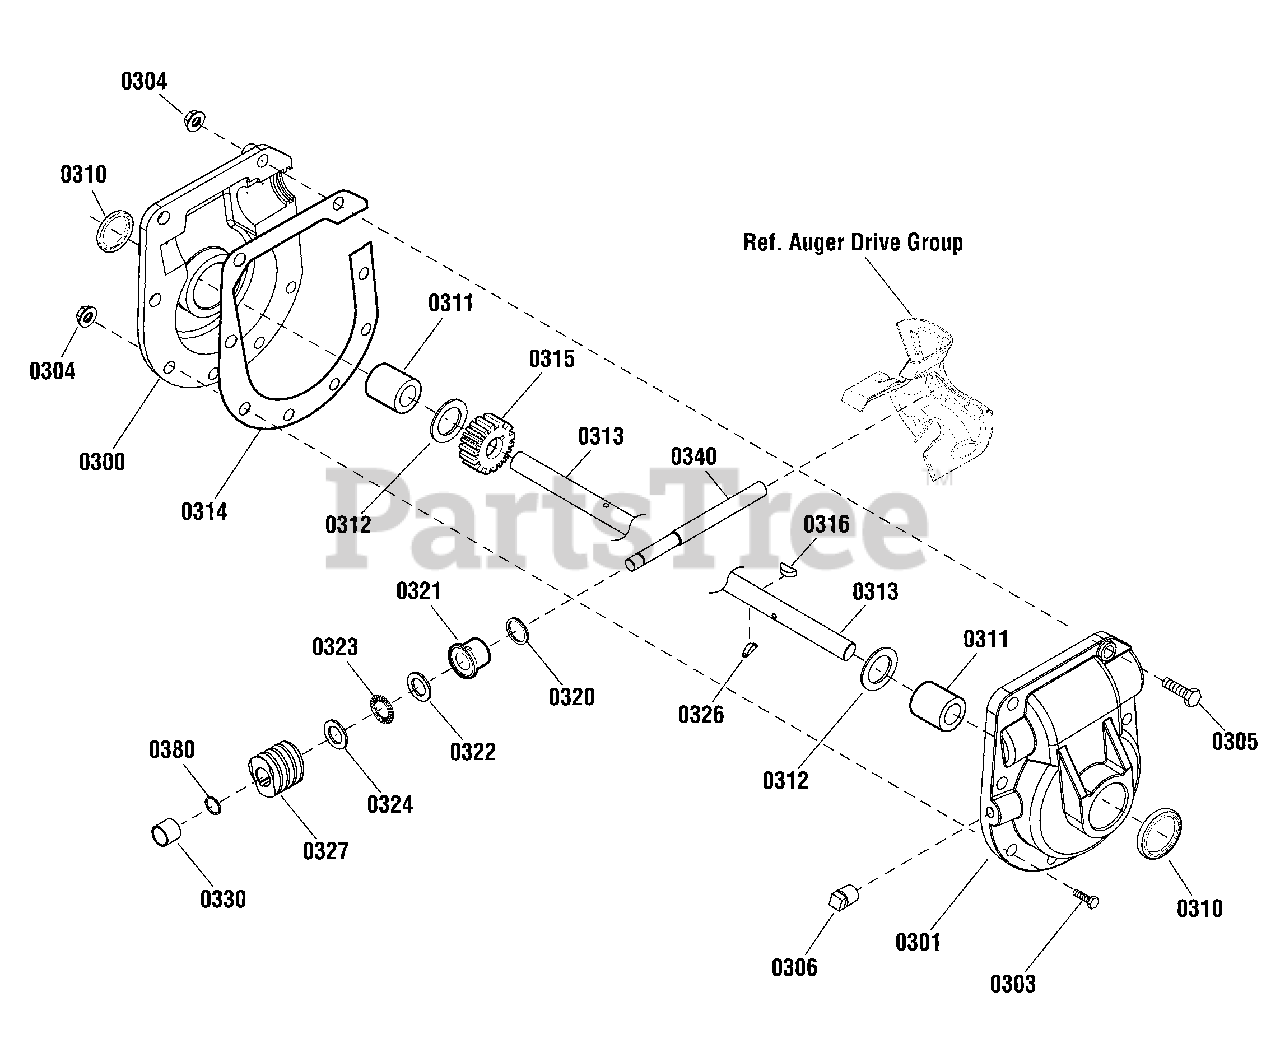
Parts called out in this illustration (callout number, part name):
300	CASE, Gear, RH
301	CASE, Gear, LH
303	BOLT, Hex, 5/16-24 x 1
304	NUT, Hex Flange, Serrated Lock, 5/16-24
305	CAPSCREW, Hex Head, 5/16-24
306	PLUG, Pipe
310	SEAL, Oil
311	BEARING, Sleeve, 1 x 1-1/4 x 1
312	WASHER, Flat, 1-1-1/2
313	SHAFT, Auger Out, 27"
314	GASKET
315	GEAR, Worm, 22T
316	KEY, Woodruff
320	RING, Quad
321	BEARING, Flange, 3/4 ID x 1-1/8 OD
322	WASHER, Thrust
323	BEARING, Roll Thrust, 3/4 ID x 1-1/4 OD
324	WASHER, Thrust
326	KEY, HI-PRO
327	WORMGEAR, 1-3/4 OD x 1-1/2"
330	BEARING, Sleeve, 3/4 ID x 7/8 OD
340	SHAFT, Impeller
380	RING, Retaining, 3/4
